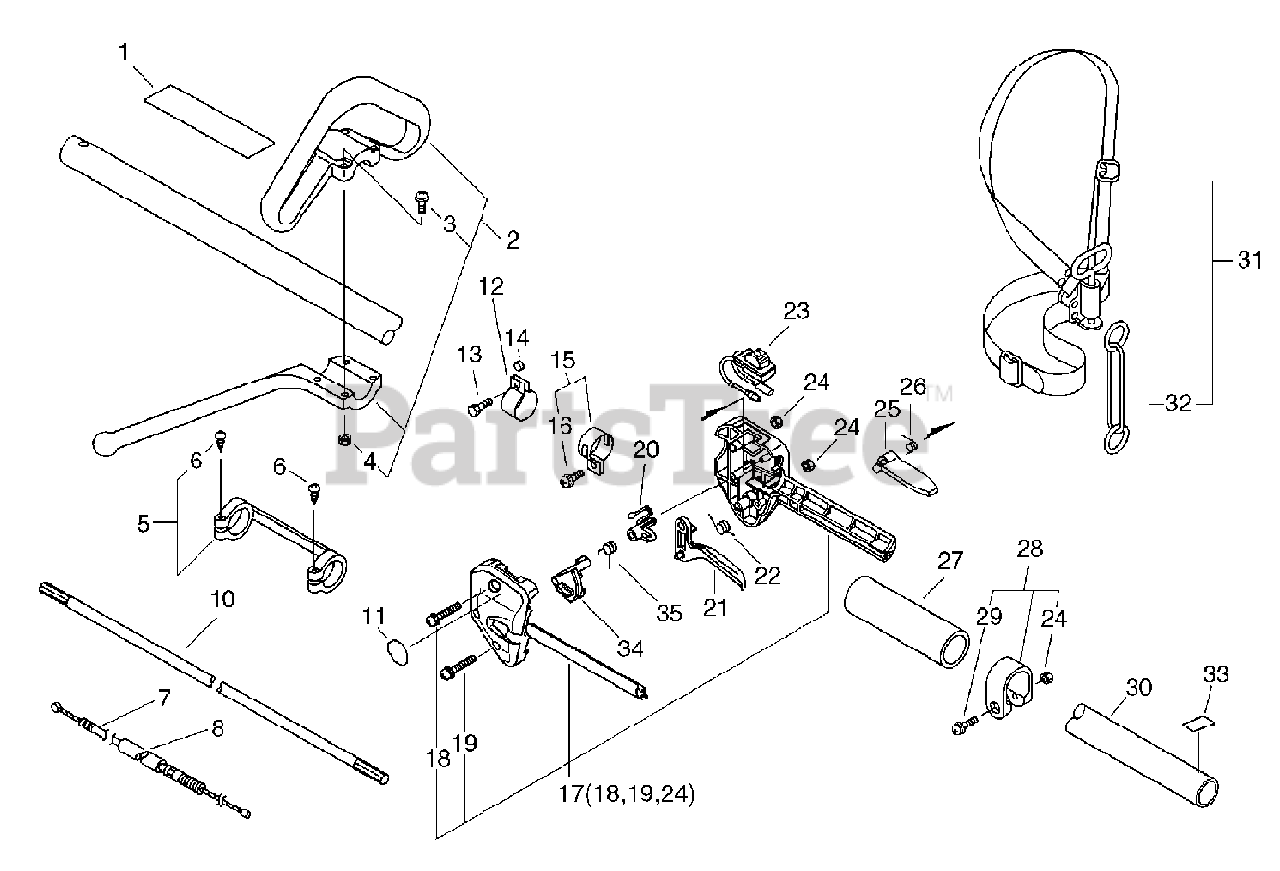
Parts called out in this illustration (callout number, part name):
1	LABEL - CAUTION
2	LOOP HANDLE ASSY
3	SCREW - 5X35
5	CLAMP KIT
6	SCREW - 4X25
7	CABLE, THROTTLE
10	DRIVESHAFT
11	LABEL - STOP
13	BOLT - 5X18
15	HOOK ASSY
16	SCREW - 5X14
17	THROTTLE BRACKET SET
18	SCREW - 5X35
19	SCREW - 5X25
20	LOCKOUT, THROTTLE
21	TRIGGER, THROTTLE
21	SPRING
22	SPRING, TRIGGER
23	SWITCH, IGNITION
25	LOCKOUT, THROTTLE
25	LEVER, TRIGGER LOCKOUT
26	SPRING, LOCKOUT LEVER
27	GRIP, HANDLE - FRONT
29	SCREW - 5X28
30	PIPE, MAIN
31	HARNESS ASSY
33	LABEL - ALIGNMENT
34	LOCKOUT, THROTTLE
35	SPRING
